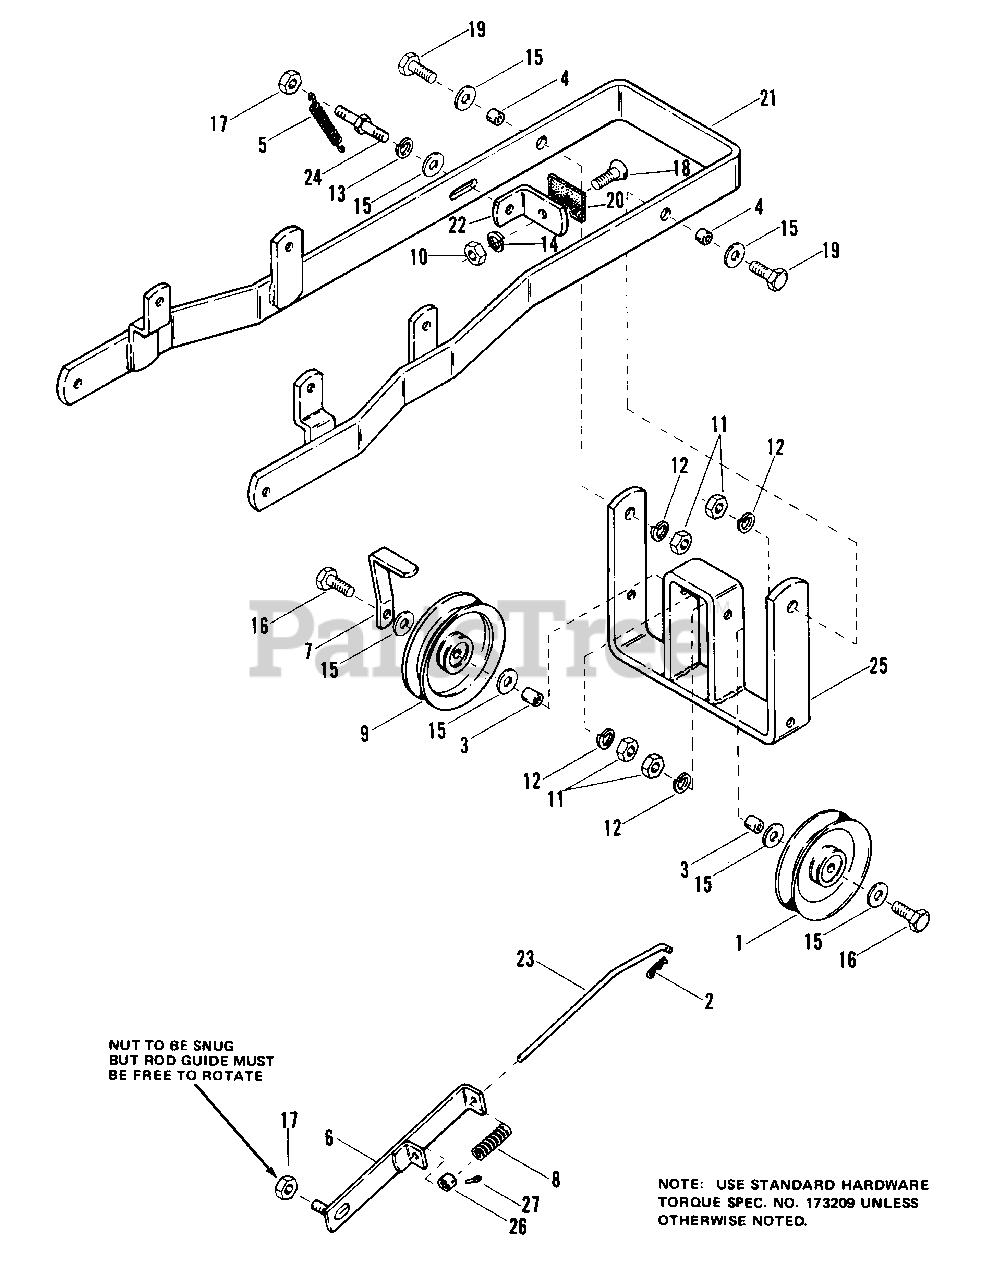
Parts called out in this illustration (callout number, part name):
2	SPRING, Clip
6	GUIDE ASSEMBLY, Clutch Rod
7	STOP, Belt
9	PULLEY, Idler
10	NUT, No. 10-24
11	NUT, 3/8-16
12	LOCKWASHER, 3/8
13	LOCKWASHER, 5/16
14	LOCKWASHER, No. 10
15	WASHER, Plain, 5/16
16	CAPSCREW, Hex Hd., 3/8-16 x 1 3/4
17	NUT, Full Lock, 5/16-18
18	SCREW, Flat Hd., No. 10-24 x 5/8
19	CAPSCREW, Hex Hd., 3/8-16 x 1 1/4
20	BRAKE SHEAVE
21	PUSH BAR ASSEMBLY
25	PIVOT PULLEY ASSEMBLY
26	COLLAR, Set
27	SETSCREW, 1/4-20 x 3/8
